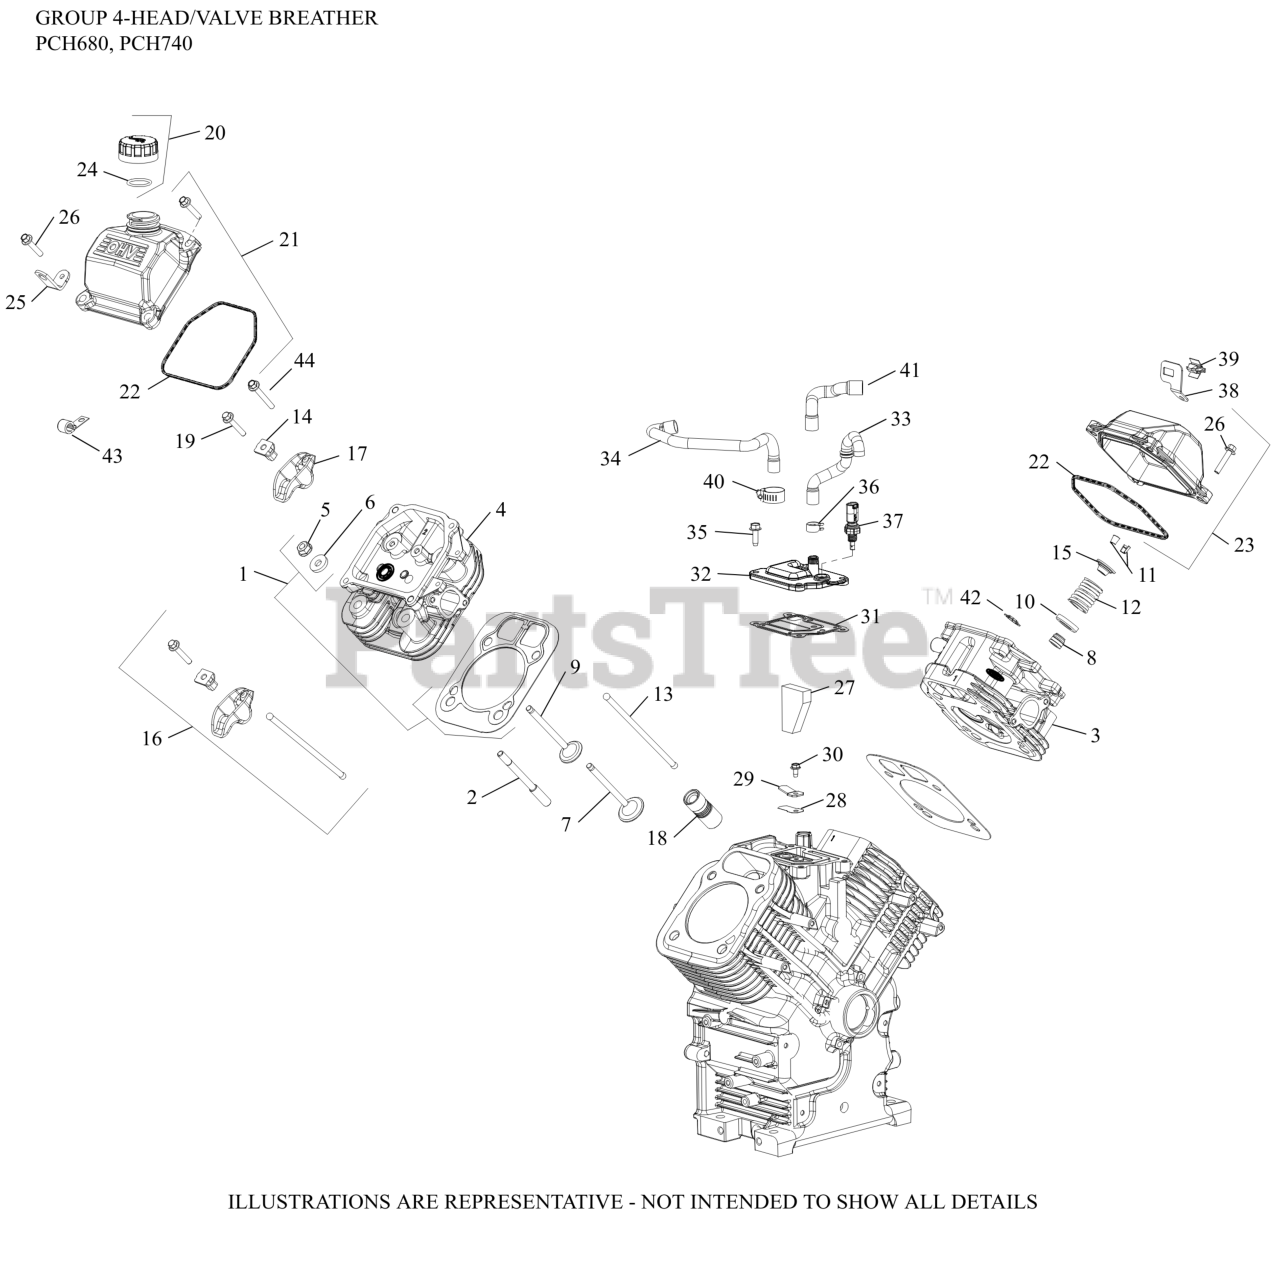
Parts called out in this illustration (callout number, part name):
1	KIT, GASKET CYLINDER HEAD
2	STUD, M8X1.25
3	HEAD, ASSY CYL (#1)-USE 24 318 216-S
4	HEAD, ASSY CYL (#2)-USE 24 318 217-S
5	NUT, FLG M8X1.25
6	WASHER, FLAT 8.6 MM
7	VALVE, INTAKE (STD)
7	VALVE, INTAKE (.25)
8	SEAL, VALVE BAND
9	VALVE, EXHAUST
9	VALVE, EXHAUST (.25)
10	RETAINER, SPRING
11	KIT, RETAINER
12	SPRING, VALVE
13	ROD, PUSH
14	PIVOT, ROCKER ARM
15	CAP, VALVE SPRING
16	KIT, VALVE TRAIN
17	ARM, ROCKER
18	LIFTER, VALVE HYDRAULIC-USE 25 351 11-S
19	SCREW, FLG (BLACK) M6X1.0X34
20	KIT, OIL FILL CAP (YELLOW)
21	KIT, VALVE COVER-OIL FILL
22	O-RING (YELLOW), VALVE CO
23	KIT, VALVE COVER-PLAIN (PLASTIC)
24	O-RING, DIPSTICK
25	STRAP, LIFTING
26	SCREW, FLG M6X1.0X30
27	FILTER, BREATHER
28	REED, BREATHER-(#2440206S)
28	REED, BREATHER
29	RETAINER, REED
30	SCREW, FLG THD FRM M5X.8X10
31	GASKET, BREATHER
32	COVER, BREATHER
34	HOSE, BREATHER - EFI HORIZONTAL
36	SPRING CLAMP, HOSE
37	SENSOR, TEMPERATURE
38	BRACKET, OXYGEN SENSOR
39	CLIP, O2 SENSOR
42	RETAINER, VALVE GUIDE (KM)
NI	SCREW, THREAD FORMING
